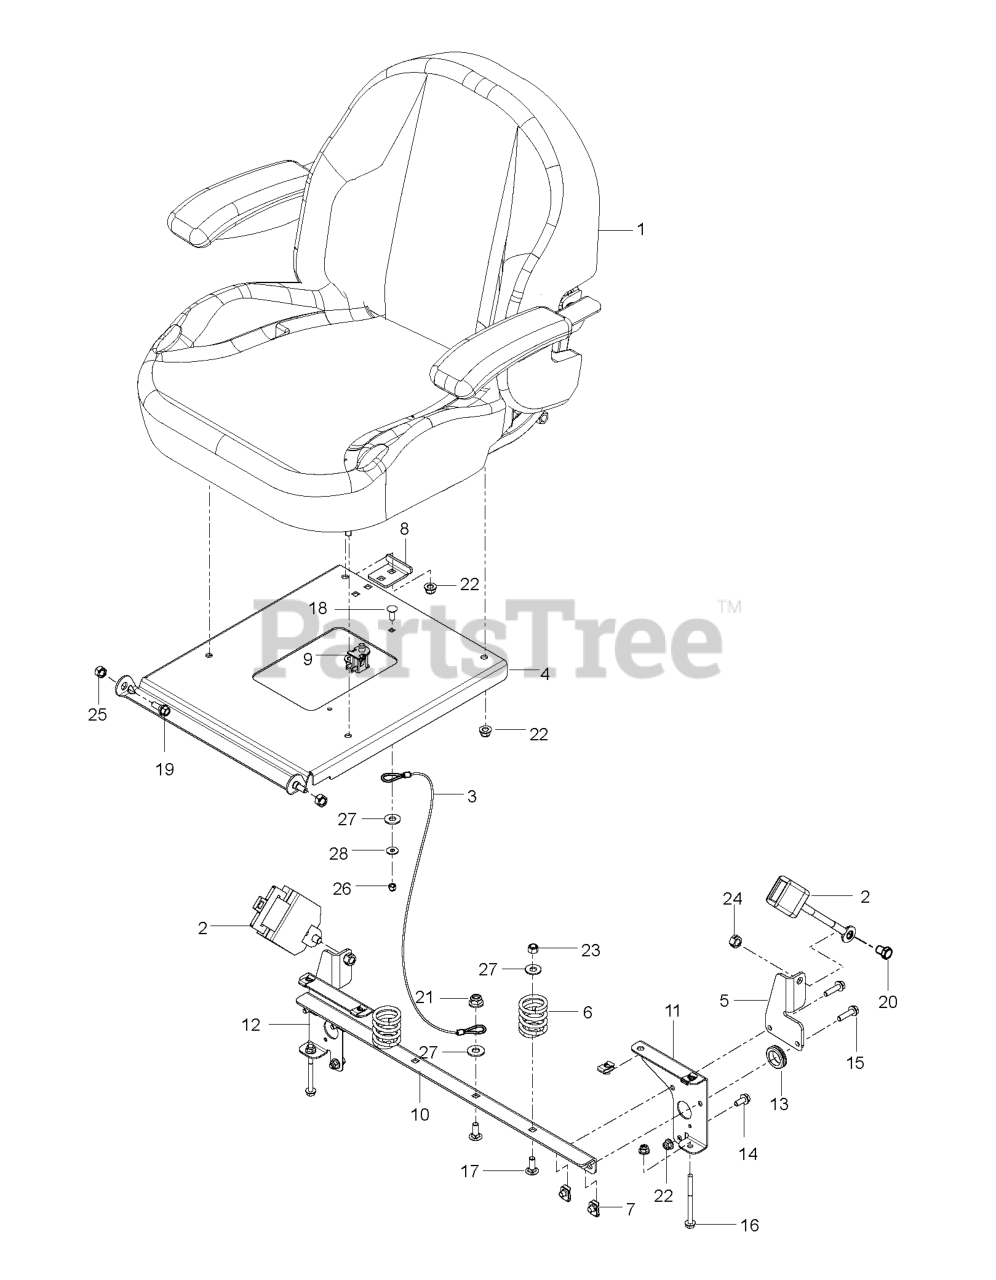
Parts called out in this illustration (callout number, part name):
1	SEAT C1110 EVC REDMAX
2	SEAT BELT - RETRACTABLE
3	SEAT LANYARD
4	SUPPORT SEAT SNAPPER RED X672
5	MOUNT.SEAT.BELT.BLACK
6	SPRING.COMPRESSION.SEAT.BLACK
7	U-CLIP 5/16-18 NUT RETAINER
8	STOP, SEAT - BLACK
9	SEAT SWITCH
10	SUPPORT.SEAT. BLK
11	SUPPORT.RT.BLK
12	SUPPORT.LT.BLK
13	RUBBER GROMMET
14	HHFS 5/16-18 X 3/4
15	HHFS 5/16-18 X 1.25 TPBLT GD 5
16	BOLT.HEX.FLNG.5/16-18X3.75
17	RHSNB 3/8C X 1
18	1/4-20X3/4 CARR BLT
19	SB 5/16-18 HEX HD GD5, BLK ZN
20	HCS 7/16-20 X .75 GD 5
21	NUT 3/8-16 HEX FLG NYLOC ZD
22	5/16-18 NYLOC FLANGE NUT
23	NUT 3/8-16 NYLOC
24	NUT HEX 7/16F LOCK RP
25	NUT.71038.31-18.HEX.NYLOCK
26	RP_NUT 1/4-20 NYLOC
27	WASHER 3/8 FLAT
28	WASHER PM
